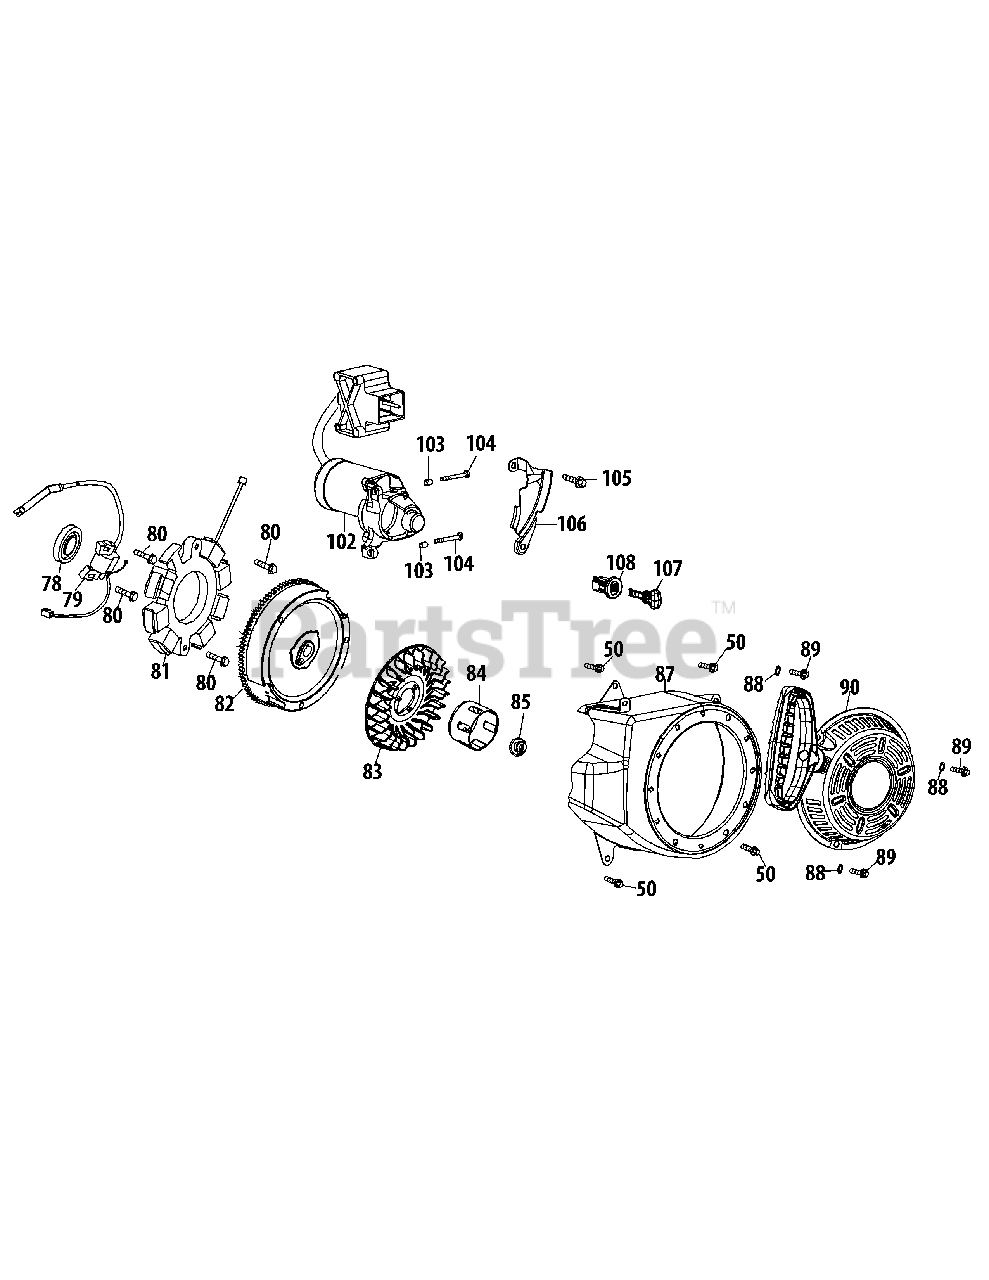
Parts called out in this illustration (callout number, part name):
50	Bolt M6×12
78	Oil Seal 25×41.25×6
79	Ignition Coil Assembly
80	Bolt M6×25
81	Alternator Assembly
82	Flywheel
83	Cooling Fan
84	Starter Cup
85	Nut, Special, M14×1.5
87	Blower Housing
88	Gasket ?6
89	Bolt M6×10
90	Recoil Starter
102	Electric Starter
103	Dowel Pin 8×8
104	Bolt M6×32
105	Bolt M6×12
106	Blower Housing Shield
107	Key
108	Key Switch Base
